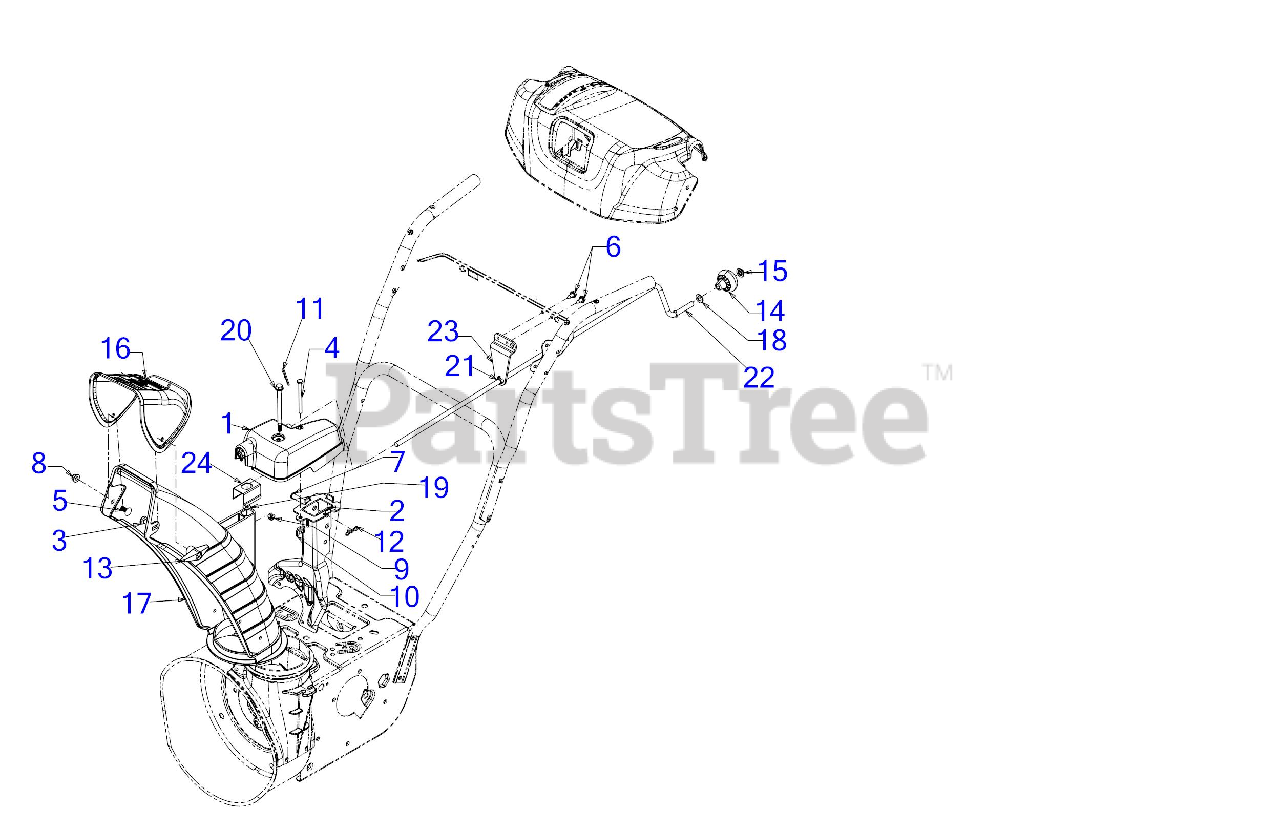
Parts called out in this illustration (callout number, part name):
1	WORM GEARBOX ASSEMBLY
3	CARRIAGE BOLT 5/16-18 x 1
4	SCREW 1/4-20 x 3.0 GR5
5	CARRIAGE BOLT 5/16-18 x .75
6	SCREW 1/4-20X.625
7	CLEVIS PIN 3/8 x 1.87
8	FLANGE LOCK NUT 5/16-18
9	FLANGE LOCK NUT
10	WING NUT 1/4-20
11	INTERNAL COTTER PIN
12	BOW TIE COTTER PIN 1/4-5/16
13	KNOB ASSEMBLY-W/NUT
14	SHIFT KNOB
15	PUSH NUT
16	UPPER CHUTE
17	LOWER CHUTE 5" DIA
18	FLAT WASHER
19	FLAT WASHER
20	SHOULDER SCREW
21	BUSHING .380 ID
23	ROD SUPPORT BRACKET
24	CHUTE BRACKET
